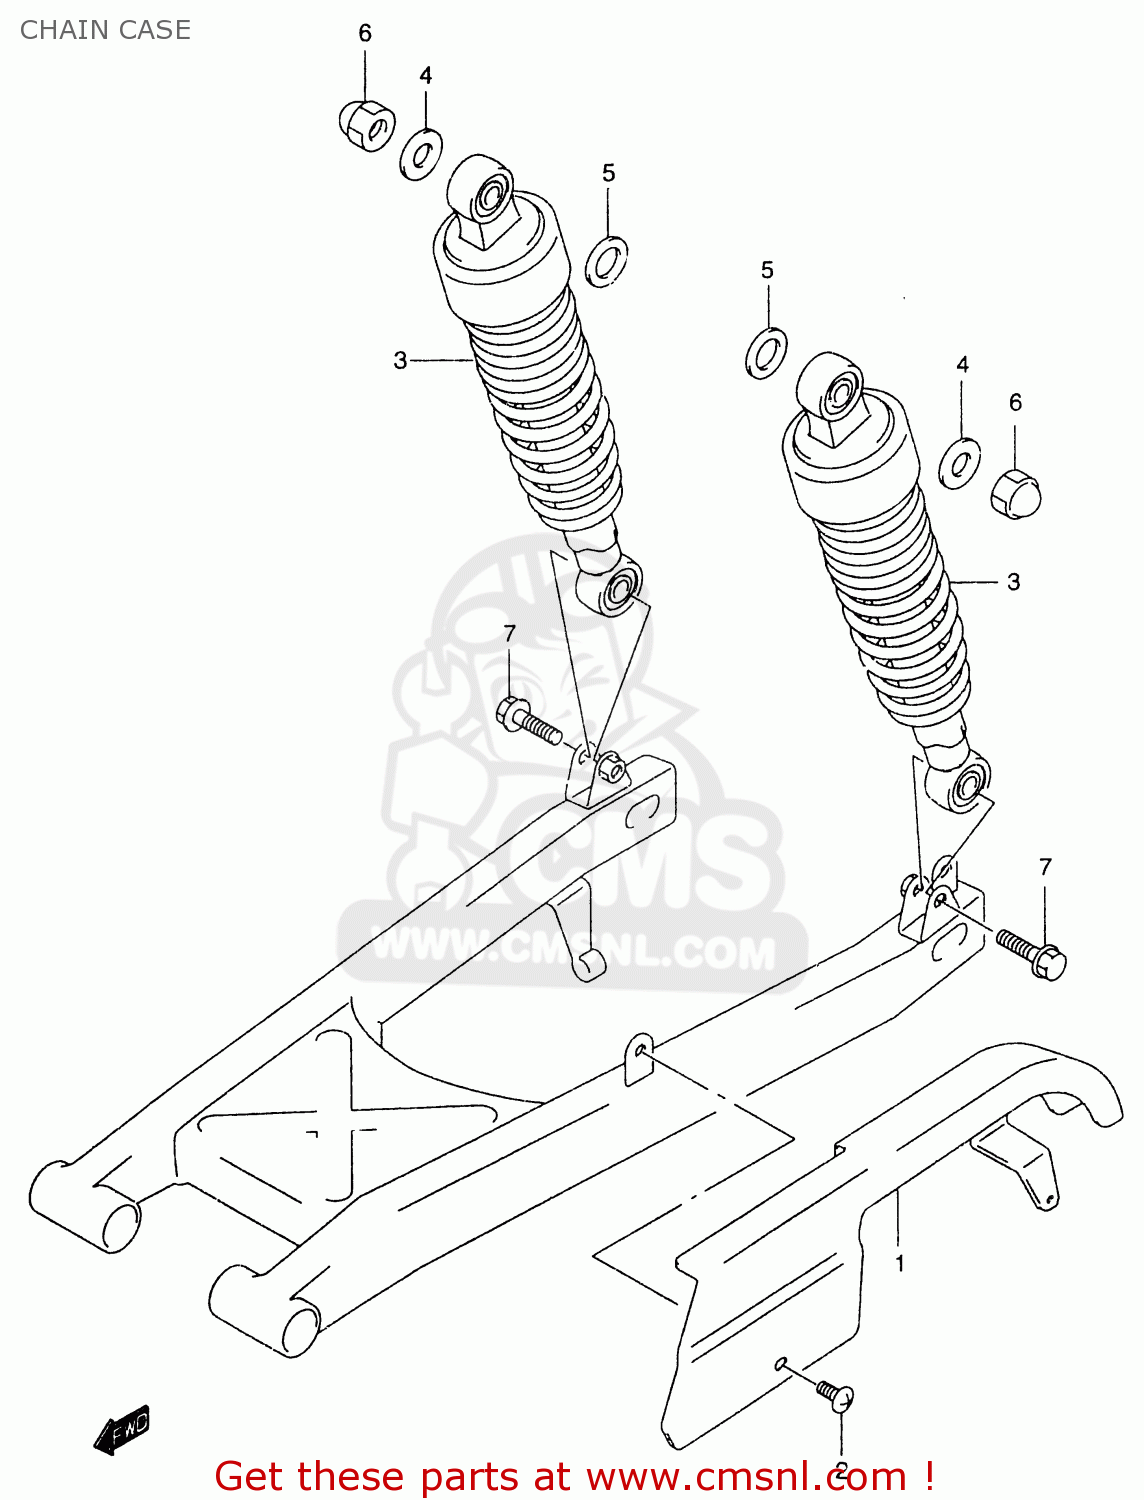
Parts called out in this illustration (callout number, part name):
1	CASE,CHAIN
2	SCREW
3	ABSORBER ASSY,RR SHOCK
4	WASHER (10.5X24X2.3)
5	WASHER
6	NUT
7	BOLT(10X37)
